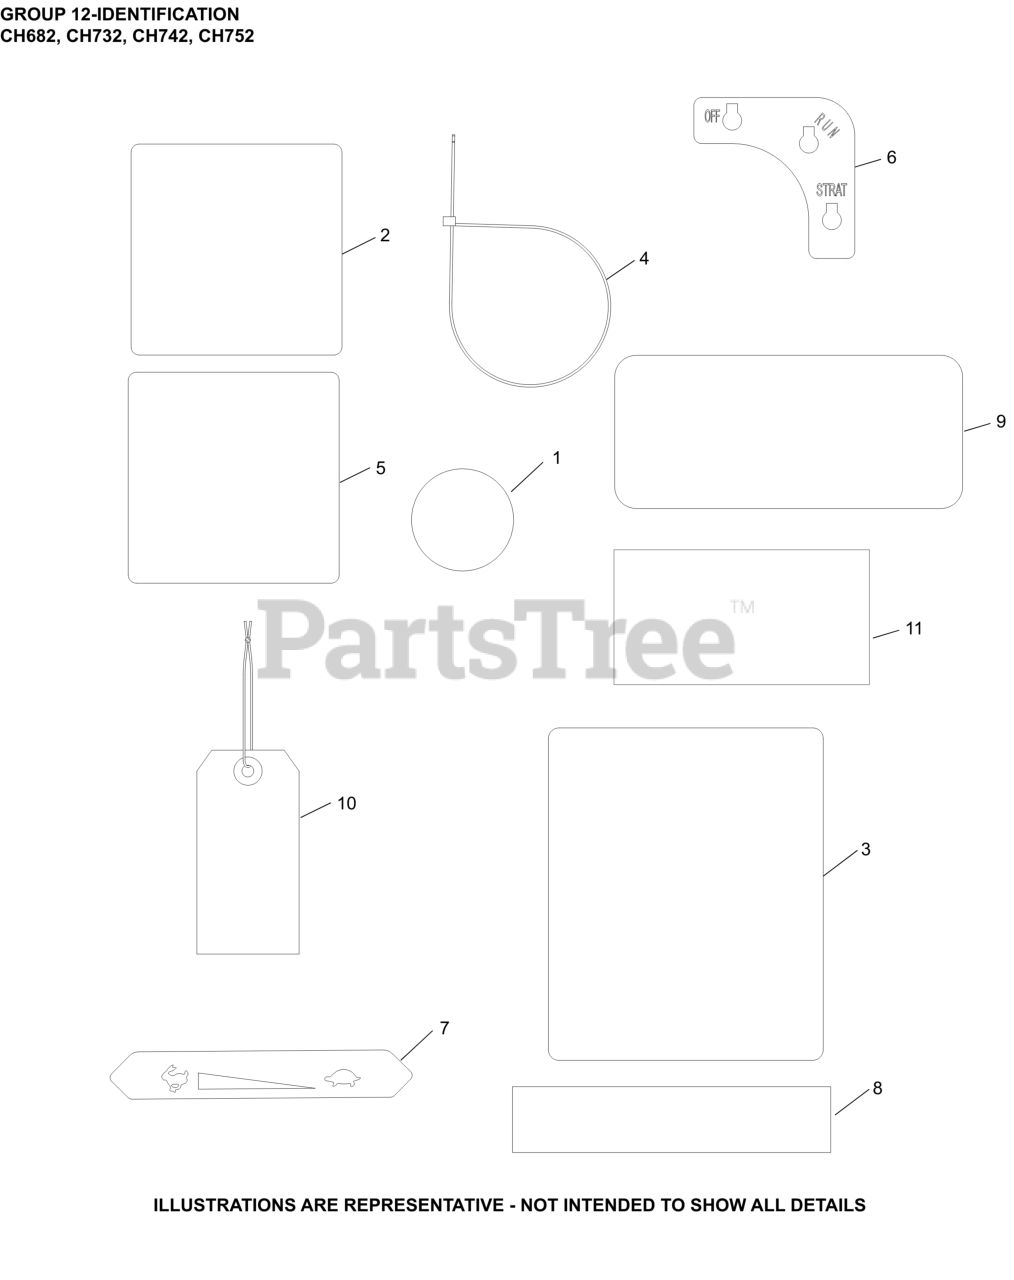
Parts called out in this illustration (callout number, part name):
1	LABEL, GRASS SCREEN
3	LABEL, CLEAR LAMINATION
5	DECAL HDAC, 25.0 HP/CV-CH742/747cc
11	DECAL, USA
